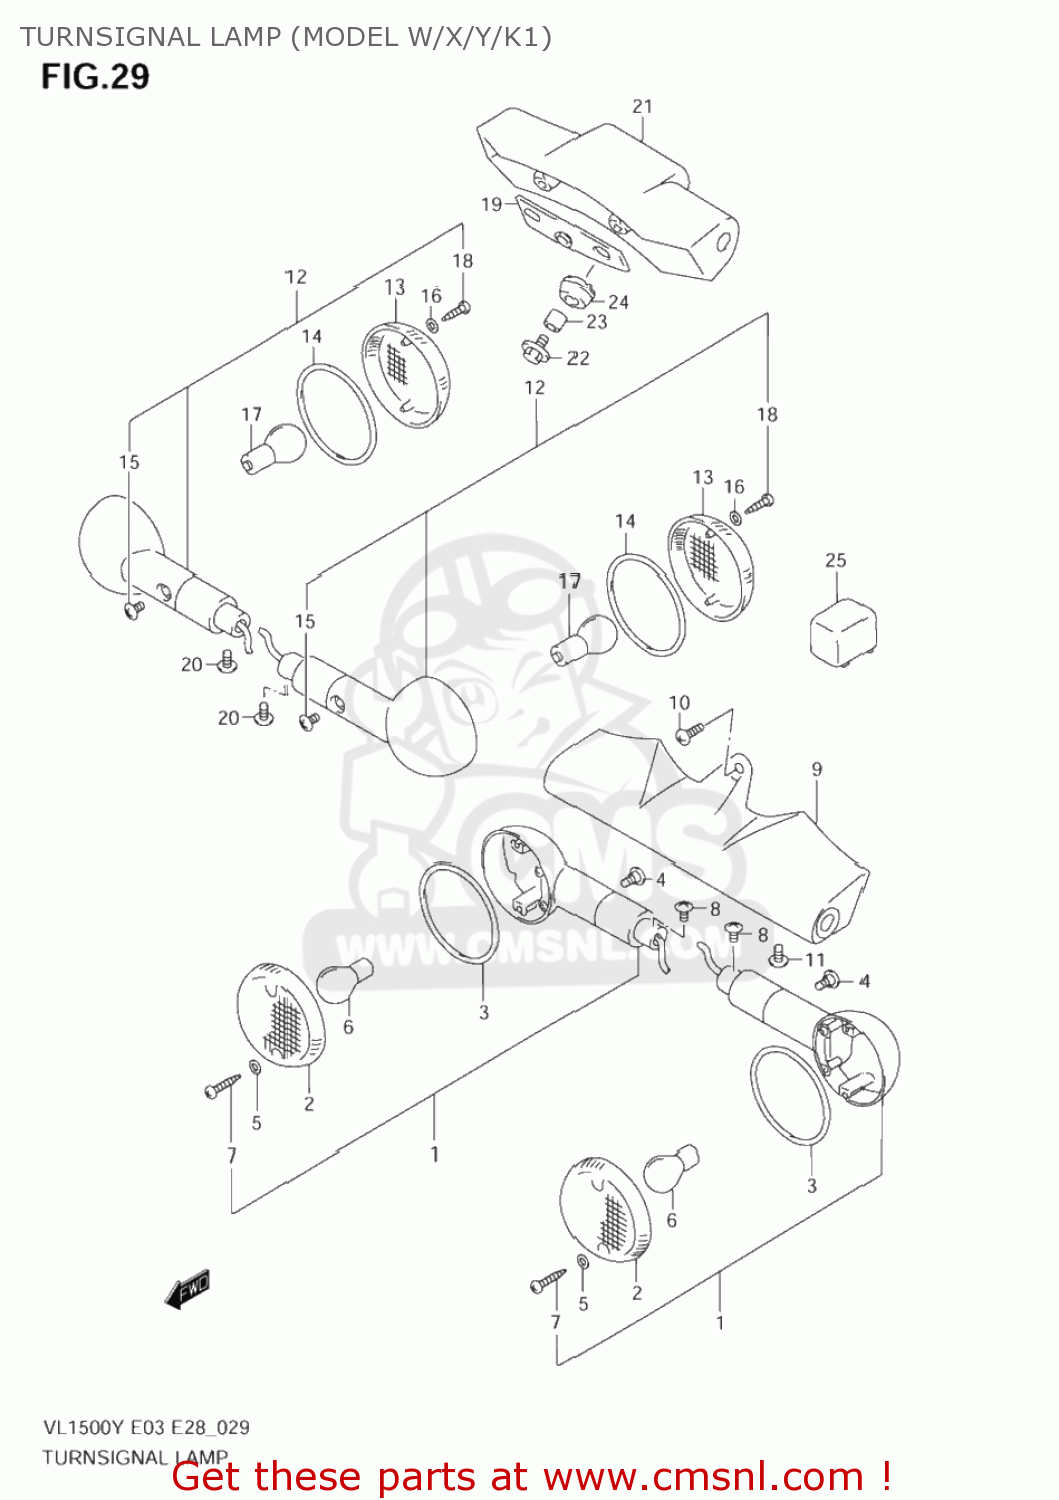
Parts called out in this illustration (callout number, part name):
1	LAMP ASSY,FR TURN SIGNAL,R
2	LENS
3	GASKET (NAS)
4	SCREW
5	GASKET (NAS)
6	BULB(12V21/5W)
7	SCREW
8	SCREW
9	STAY,FR TURNSIGNAL
10	SCREW(6X16)
11	SCREW(8X16)
12	LAMP ASSY,RR TURNSIGNAL,R
13	LENS
14	GASKET (NAS)
15	SCREW
16	GASKET (NAS)
17	BULB(12V21W)
18	SCREW
19	CUSHION,RR TURN STAY
20	SCREW
21	STAY,RR TURNSIGNAL
22	BOLT(6X20)
23	SPACER(6.5X10X10)
24	CUSHION
25	RELAY ASSY,TURNSIGNAL LAMP
